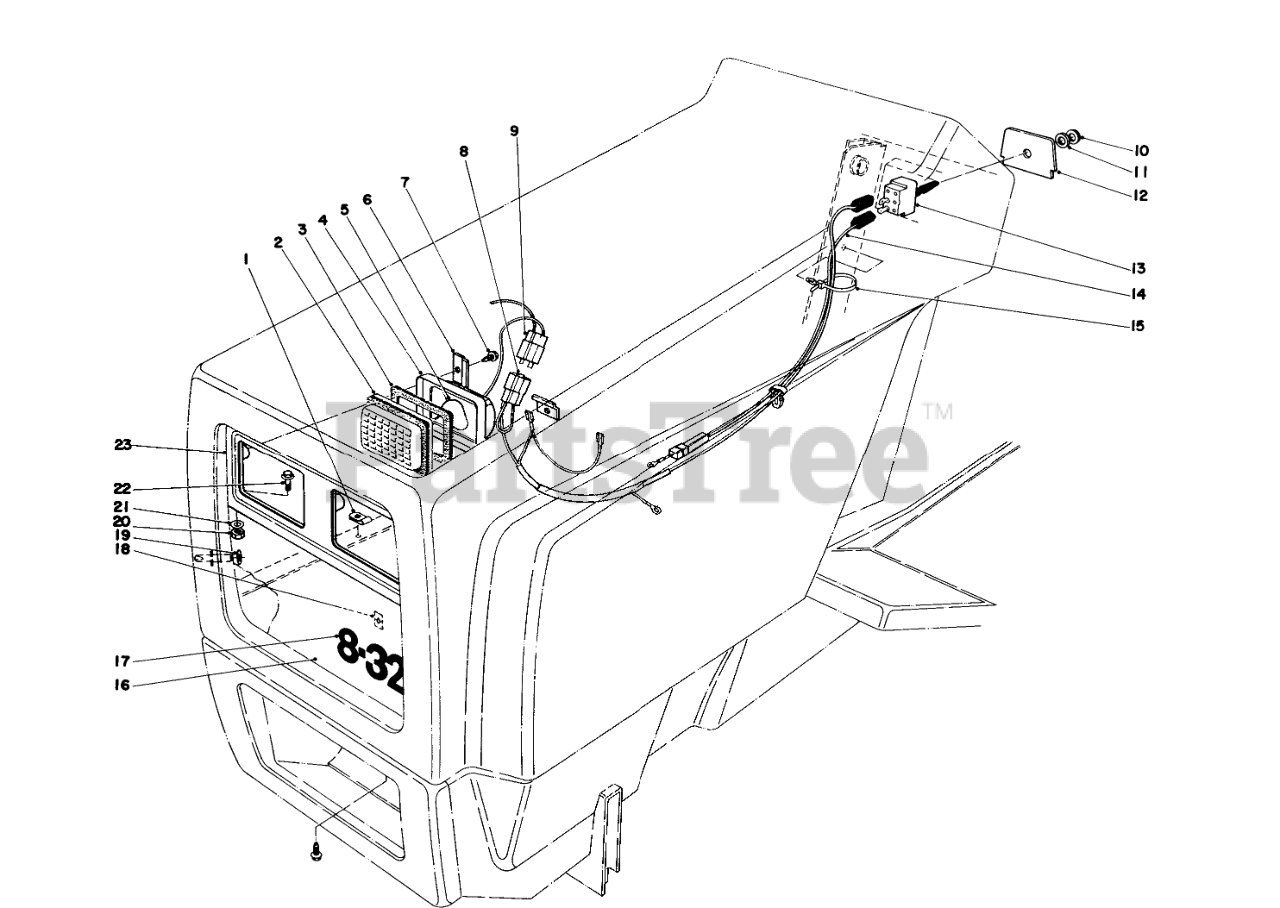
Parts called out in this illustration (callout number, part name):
1	CABLE CLAMP
2	Lens
3	Gasket Lens
4	Reflector
6	HEADLIGHT CLAMP
7	SCREW-HWHTF
8	CONNECTOR BODY
9	SOCKET
10	NUT-BULB
11	NUT-LOCK
12	DASH PANEL INSERT
13	LIGHT SWITCH
14	WIRE HARNESS
15	TIE-CABLE
16	Grille Headlight
17	Nameplate Grille
19	WASHER
20	NUT-LOCK, SIDE
21	WASHER-FLAT
22	SCREW-SHWH
23	HEADLIGHT PANEL B
